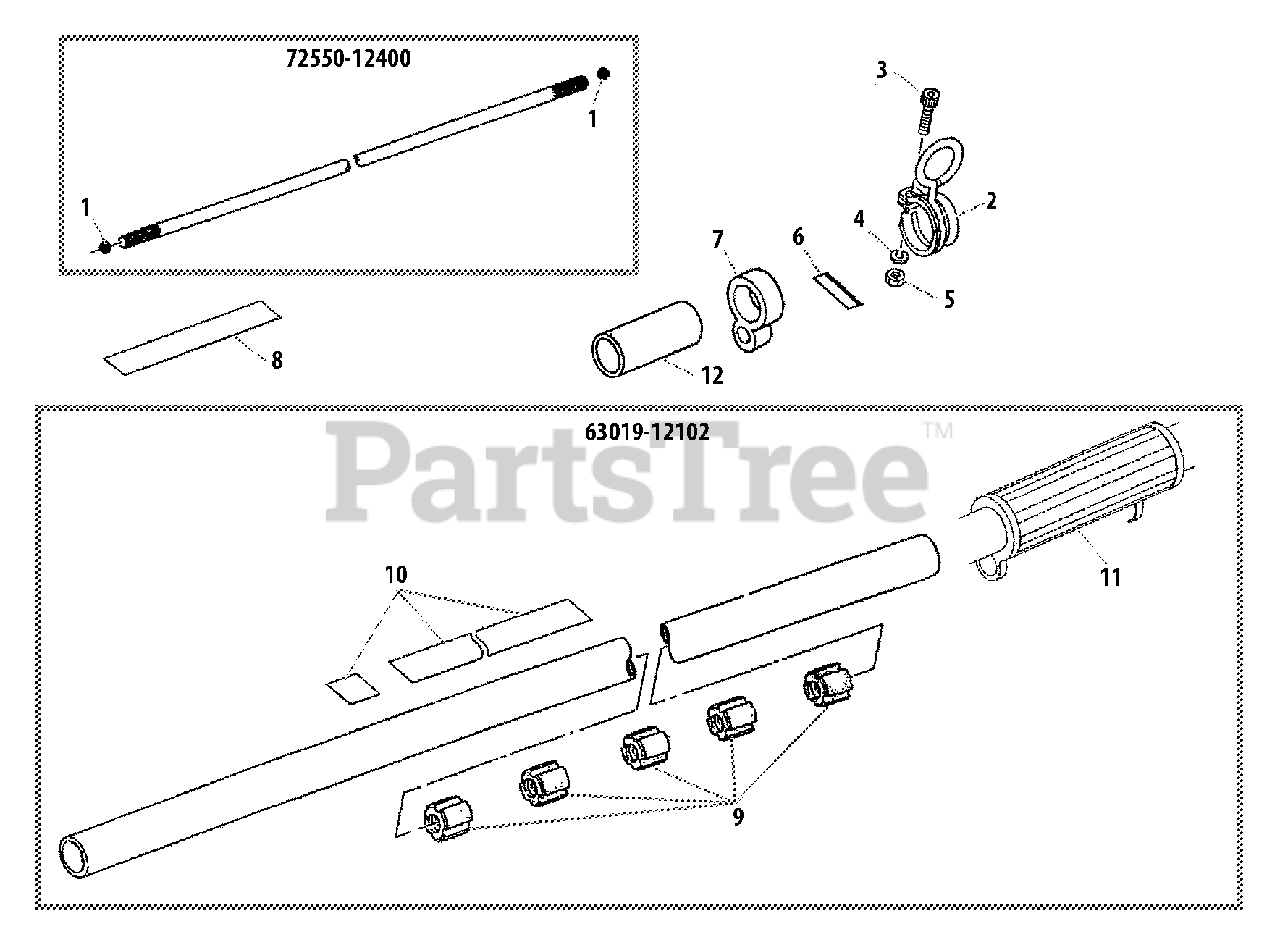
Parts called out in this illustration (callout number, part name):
1	STOPPER
2	HANGER
3	SCREW - 5X12
4	LOCKWASHER - 5
6	LABEL - HANDLE LOCATION
7	BAND
8	LABEL - MODEL
9	BUSHING
10	LABEL - CAUTION
11	GRIP
12	PROTECTOR
63019-12102	MAIN PIPE ASSY
72550-12400	DRIVESHAFT ASSY
